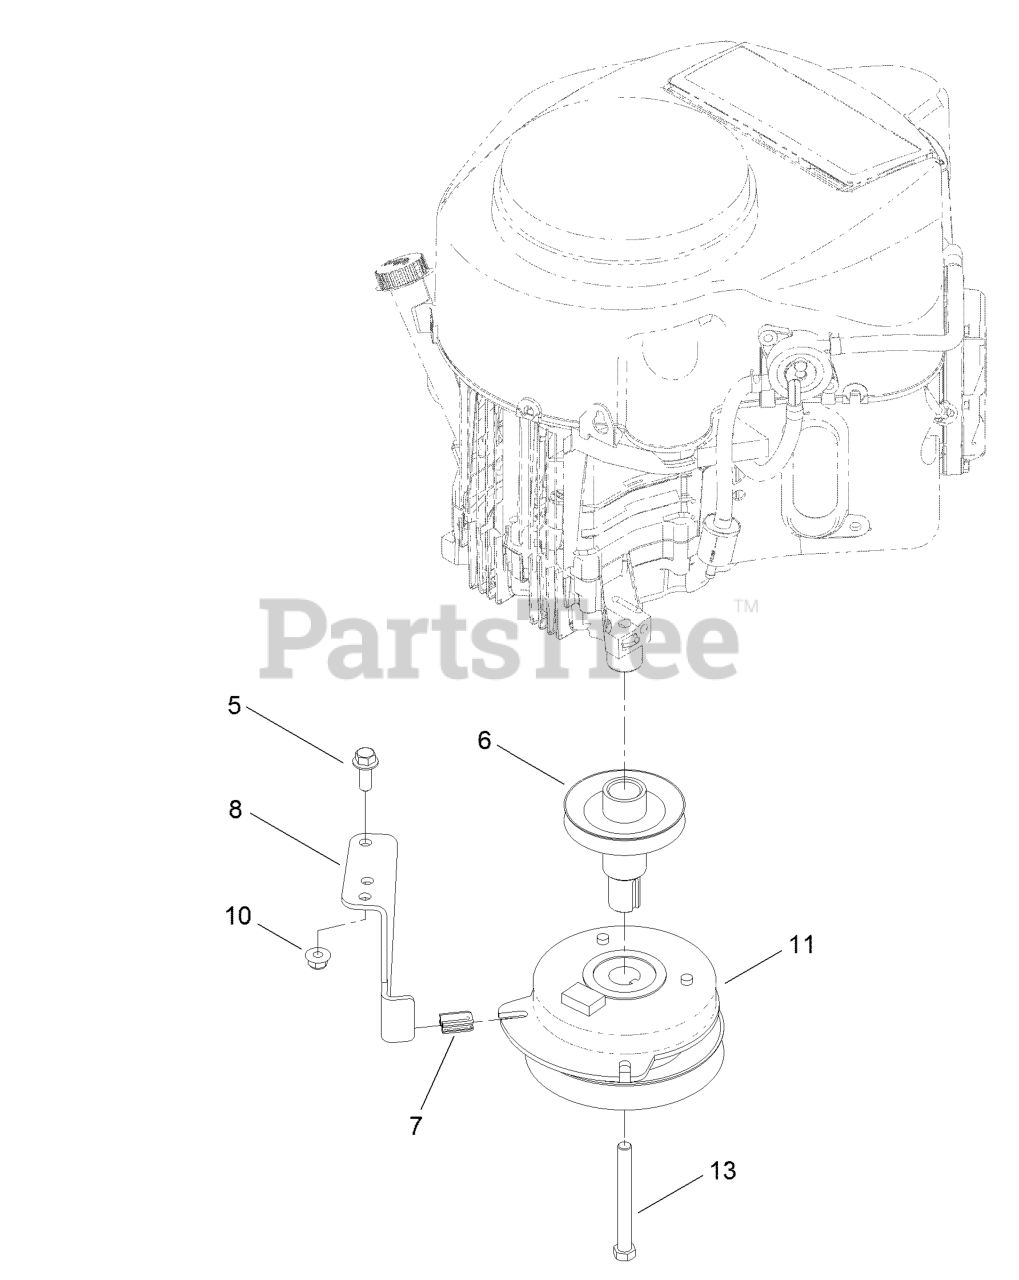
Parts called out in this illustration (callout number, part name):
5	SCREW-HHF 3/8-16 X 1
6	PULLEY-ENGINE
7	ISOLATOR-CLUTCH
8	STOP-CLUTCH
10	NUT-HF, NI
11	CLUTCH-ELECTRIC, PTO
13	SCREW-HH
